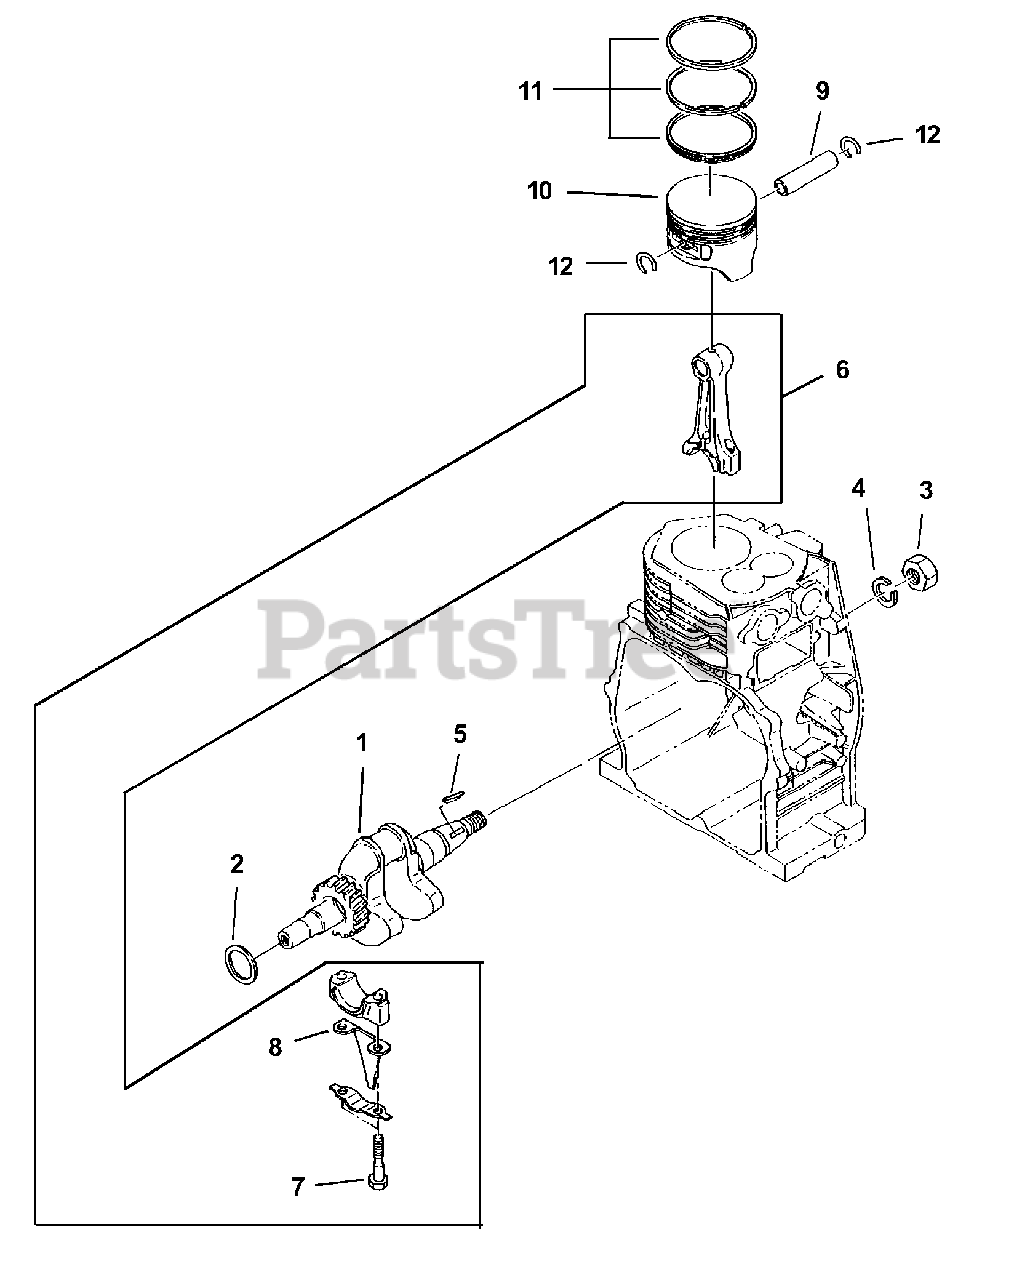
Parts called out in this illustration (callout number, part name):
1	Crankshaft
2	Spacer (.6)
3	Nut (M18 X 1.5)
4	Spring washer
5	Woodruff key
6	Connecting rod
7	Connecting rod bolt (M7 X 1.0 X 38L)
8	Oil scraper
9	Piston pin
11	Piston ring set (std)
